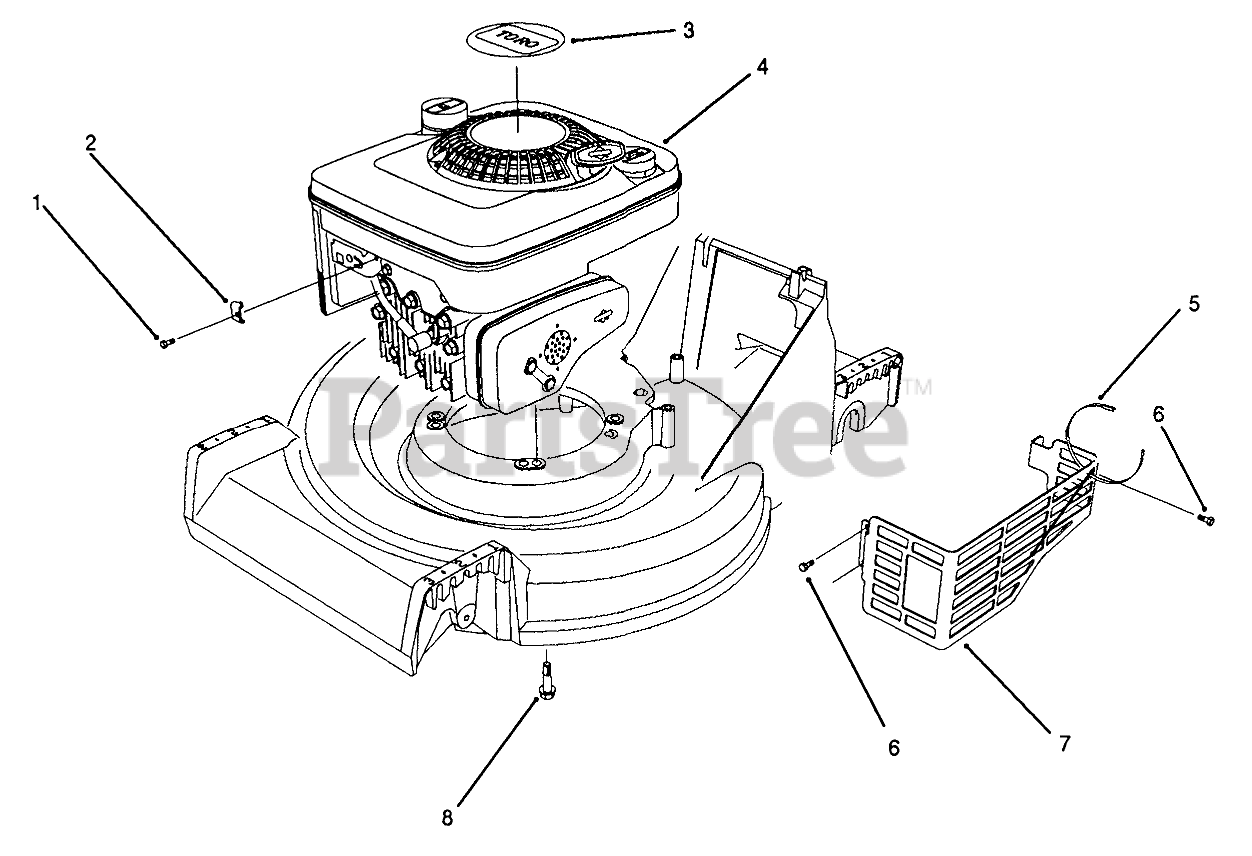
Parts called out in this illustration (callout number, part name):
1	Screw
2	CLAMP-CASING
3	DECAL - ENGINE
5	TIE-CABLE
6	SCREW-HWH
7	SHIELD-MUFFLER
8	SCREW-HWH
